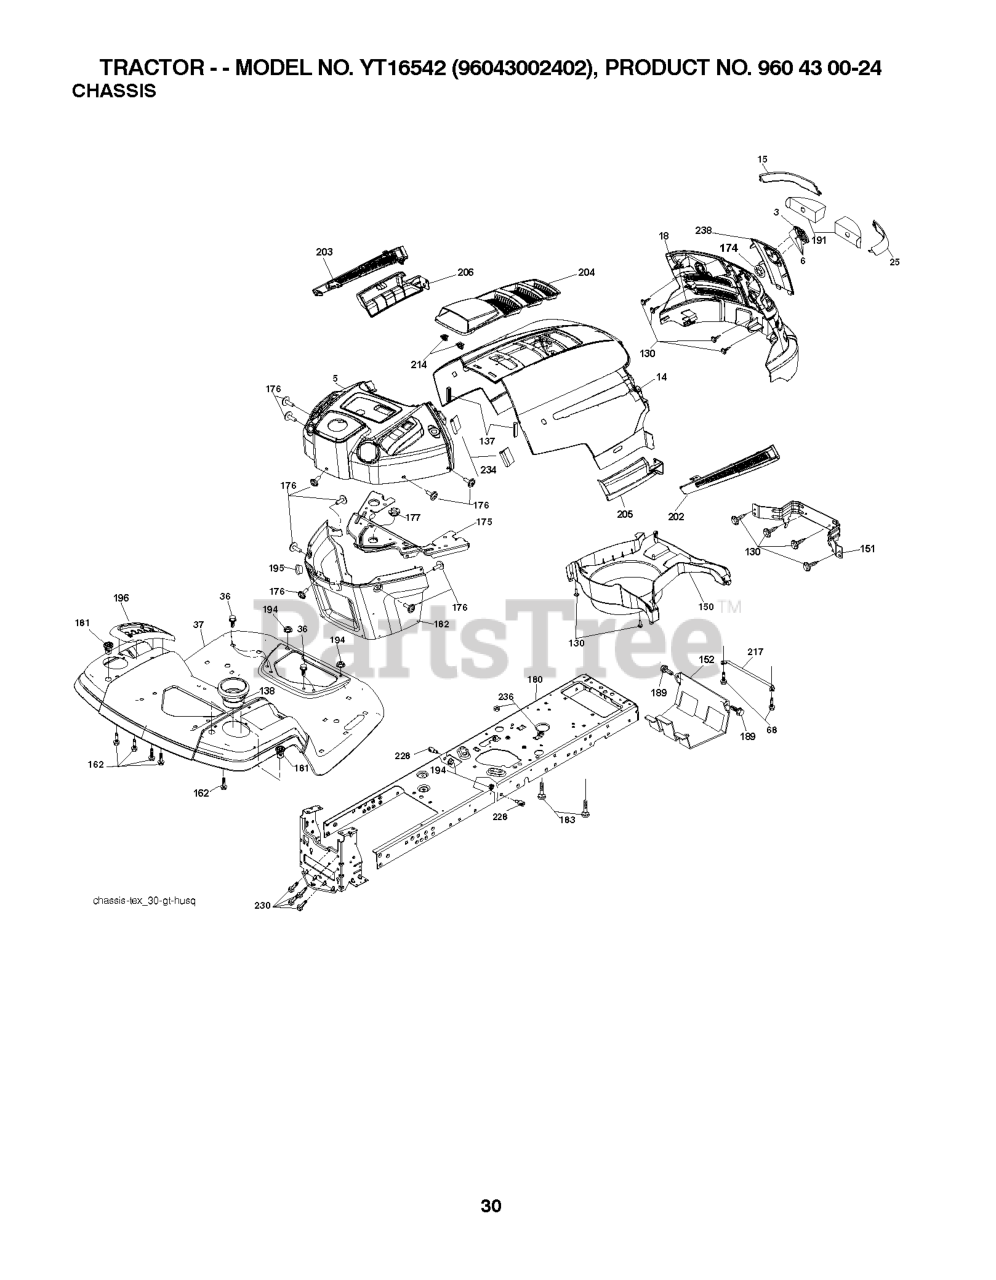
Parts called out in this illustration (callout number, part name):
3	RP LOGO
5	DASH
14	HOOD
15	LENS.HUSQVARNA LT.LH
18	RP GRILLE/LENS ASM.
25	LENS.HUSQVARNA LT.RH
36	SCREW 3/8-16X3/4
37	FENDER.REAR.ORANGE
68	Screw 5/16-18 x 1/2 Hex, Self Tapping 5/16-18 x 1/2
130	SCREW
138	CUPHOLDER.TL.TEX.418
151	BRACKET PIVOT
152	SHIELD.BROWNING/DEBRIS
162	SCREW.HI-LO.CONSOLE
175	CROSSMEMBER
176	SCREW.#10-24X5/8.RN.QU
177	BUSHING STEERING
180	CHASSIS.STAMPING.LT/GT
181	BUSHING.MNT.FEND.CRGO.
182	DASH LOWER
183	BOLT.5/16-18X1-1/4 FULL.THREAD
189	SCREW
191	INSERT REFLECTIVE
194	NUT LOCK HEX FLANGE 5/16-18
195	PLUG DASH
196	CONSOLE.ASM.DECK.LIFT.
202	VENT SIDE HOOD RH
203	VENT SIDE HOOD LH
204	VENT TOP HOOD
205	SKIRT SIDE RH
206	SKIRT SIDE LH
214	CLIP.RETAINER.TINNER.
217	ROD PIVOT CHASSIS/HOOD
228	STUD.FASTNER.W/ANTI-ROTATE
230	SHOULDER BOLT 5/16-18TT
234	BUMPER.HOOD.TEX.HUSQVARNA
236	NUT.CENTERLOCK.5/16-
238	TRIM
